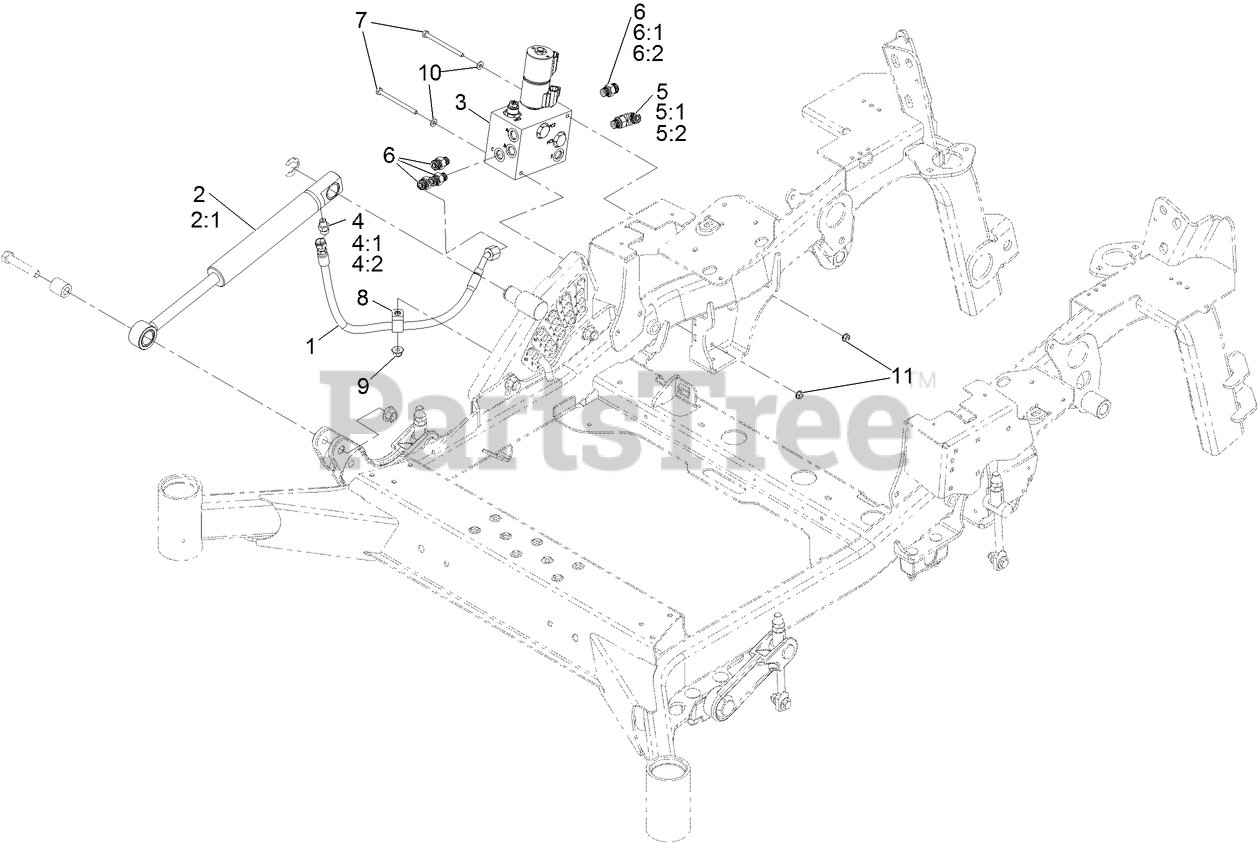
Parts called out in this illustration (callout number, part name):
1	HOSE ASM
2	CYLINDER-LIFT
2:1	KIT, CYL REPAIR
3	LIFT AND HOLD VALVE ASM
4	FITTING-HYD, STRAIGHT
4:1	O-RING
4:2	O-RING
5	FITTING-ELBOW, 90 DEG
5:1	O-RING
5:2	O-RING
6	FITTING-STRAIGHT
6:1	O-RING
6:2	O-RING
7	SCREW-HH
8	CLIP-LOOM
9	NUT-HF, NI
10	WASHER-FLAT
11	NUT-HF
